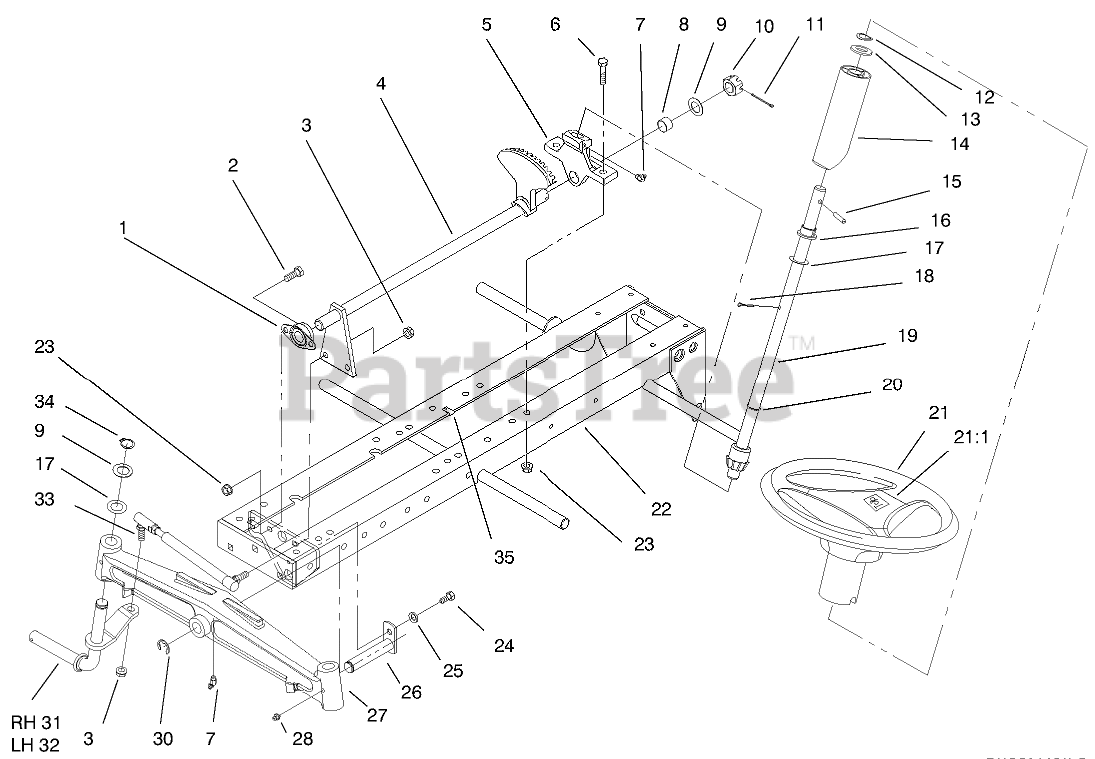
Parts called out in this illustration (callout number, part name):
1	BEARING-FLANGED
2	SCREW-HH
3	NUT-LOCK
4	LOWER STEERING ASM
5	SUPPORT-LOWER, STEERING
6	SCREW-HH
7	FITTING-LUBE, 45 DEG
8	BEARING-BRONZE
9	WASHER
10	NUT-HEX, SLOTTED
11	PIN-COTTER
12	WASHER-BOWED
13	WASHER-FLAT
14	TUBE-STEERING
15	PIN-ROLL
16	BEARING-FLANGED
17	WASHER-SHIM
18	PIN-COTTER
19	STEERING SHAFT ASM
20	O-RING
21	WHEEL - STEERING 15"
21:1	COVER-WHEEL
22	FRAME ASM
23	NUT-LOCK, NI
24	SCREW-HH
25	WASHER-LOCK
26	PIN AND PLATE ASM
27	AXLE-FRONT
28	FITTING-GREASE
30	E-RING
31	SPINDLE ASM-RH
32	SPINDLE ASM-LH
33	TIE ROD ASM
34	RING-RETAINING
